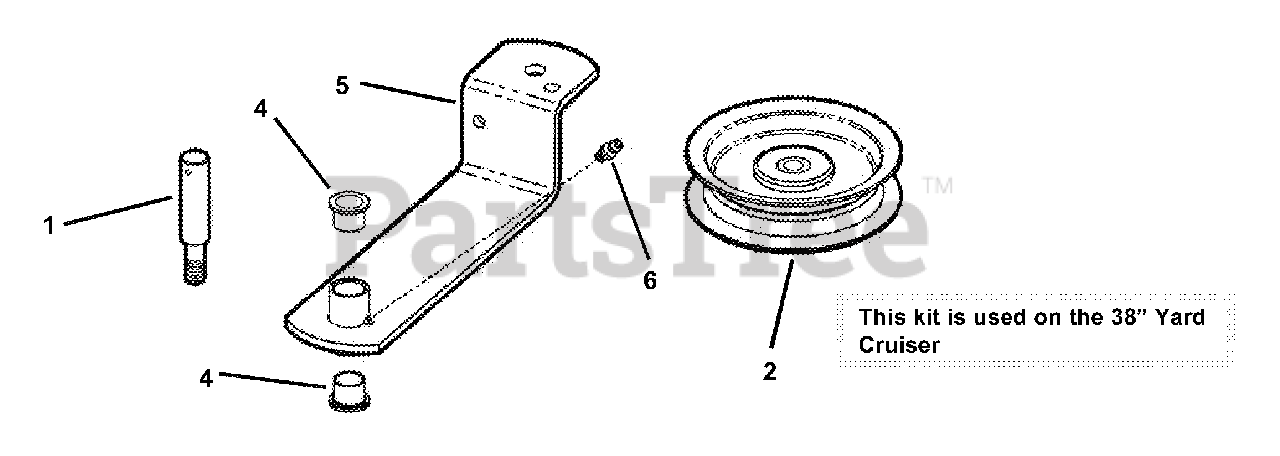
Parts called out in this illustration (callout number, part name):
1	STUD, Idler (5/16-24 Thread)
2	IDLER, 4.00 O.D. Flat
3	ASSEMBLY, Idler Arm (38" Deck)
4	BUSHING, 1/2" Nylon
5	WELDMENT, Idler Arm (38" Deck)
6	LUBE FITTING, Straight (press-fit for .187 dia. Hole)
